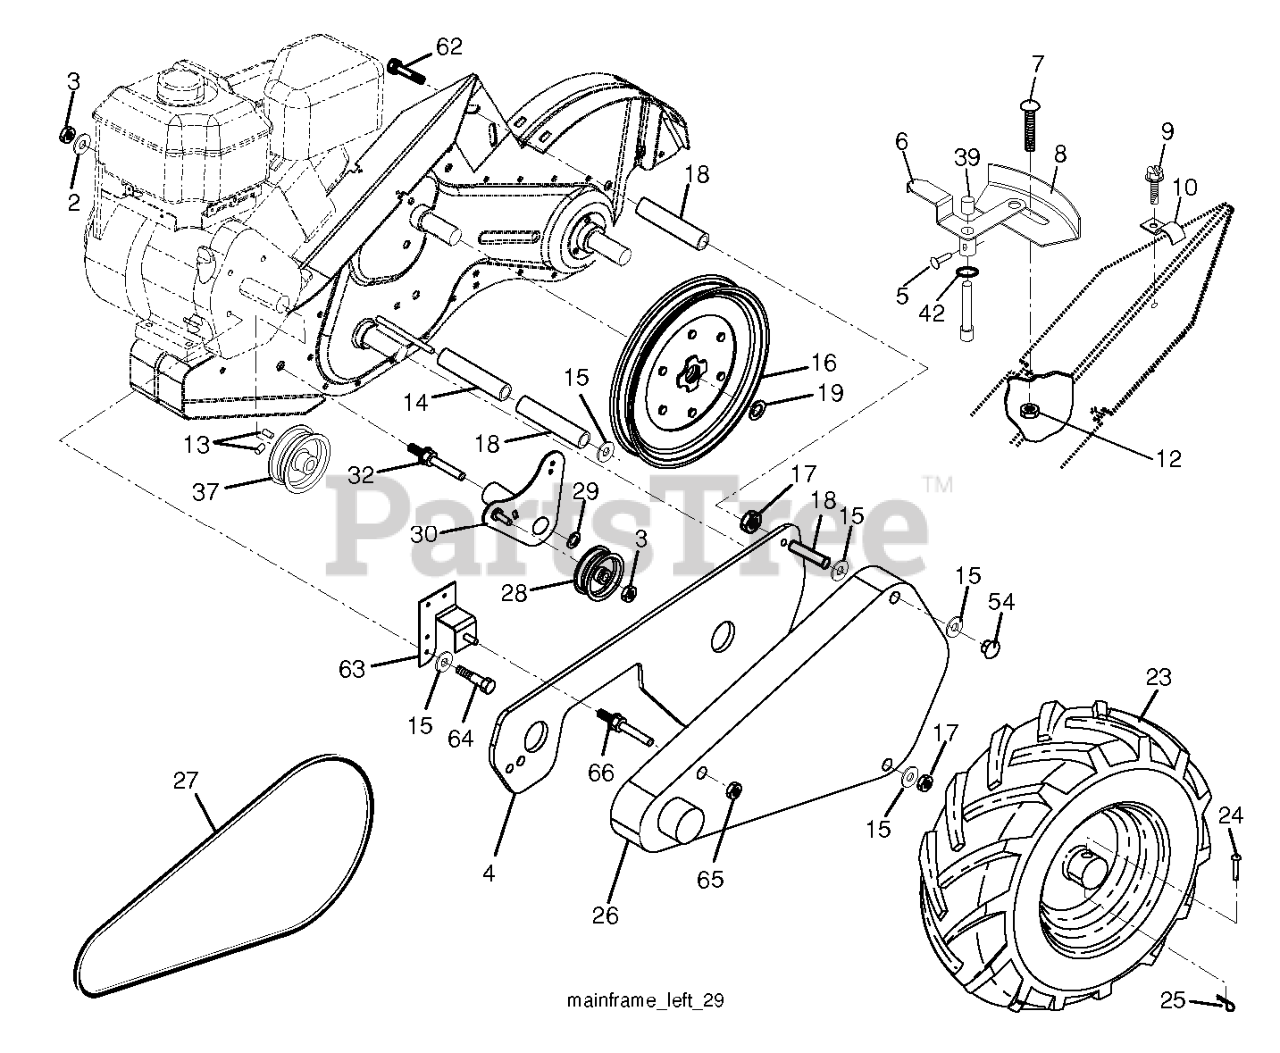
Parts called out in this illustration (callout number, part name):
2	WASHER, LOCK 3/8
3	NUT.HEX.3/8-16UNC
5	PIN.SPIROL.FLARED
6	LEVER ASM CRT
8	PANEL.INDICATOR.SHIFT.BLACK
9	TAPPING SCREW
10	CONDUIT.CLIP.PLATED
12	NUT
14	SPACER-SPLIT.327 X .42
15	WASHER
16	SHEAVE, TRANSMISSION
18	SPACER SPLIT
19	RETAINING RING LT
23	WHEEL.DR.RH.16X4X8.TILLER.SILV
25	SPRING TI
26	GUARD.BELT.TILLER.8HP.ORANGE
27	BELT, DRIVE
28	PULLEY-IDLER TI
30	BRACKET
32	SHAFT, IDLER ARM
37	RPSHEAVE.3.50.TILLER.ZINC.SUBA
39	CAP.PLUNGER.BLACK
62	BOLT 5/16-18X4 1/2
63	BRACKET.ASM.GRD.BELT.INTEK.PNT
66	GUIDE.BELT.REAR.TINE.TILLER.BL
